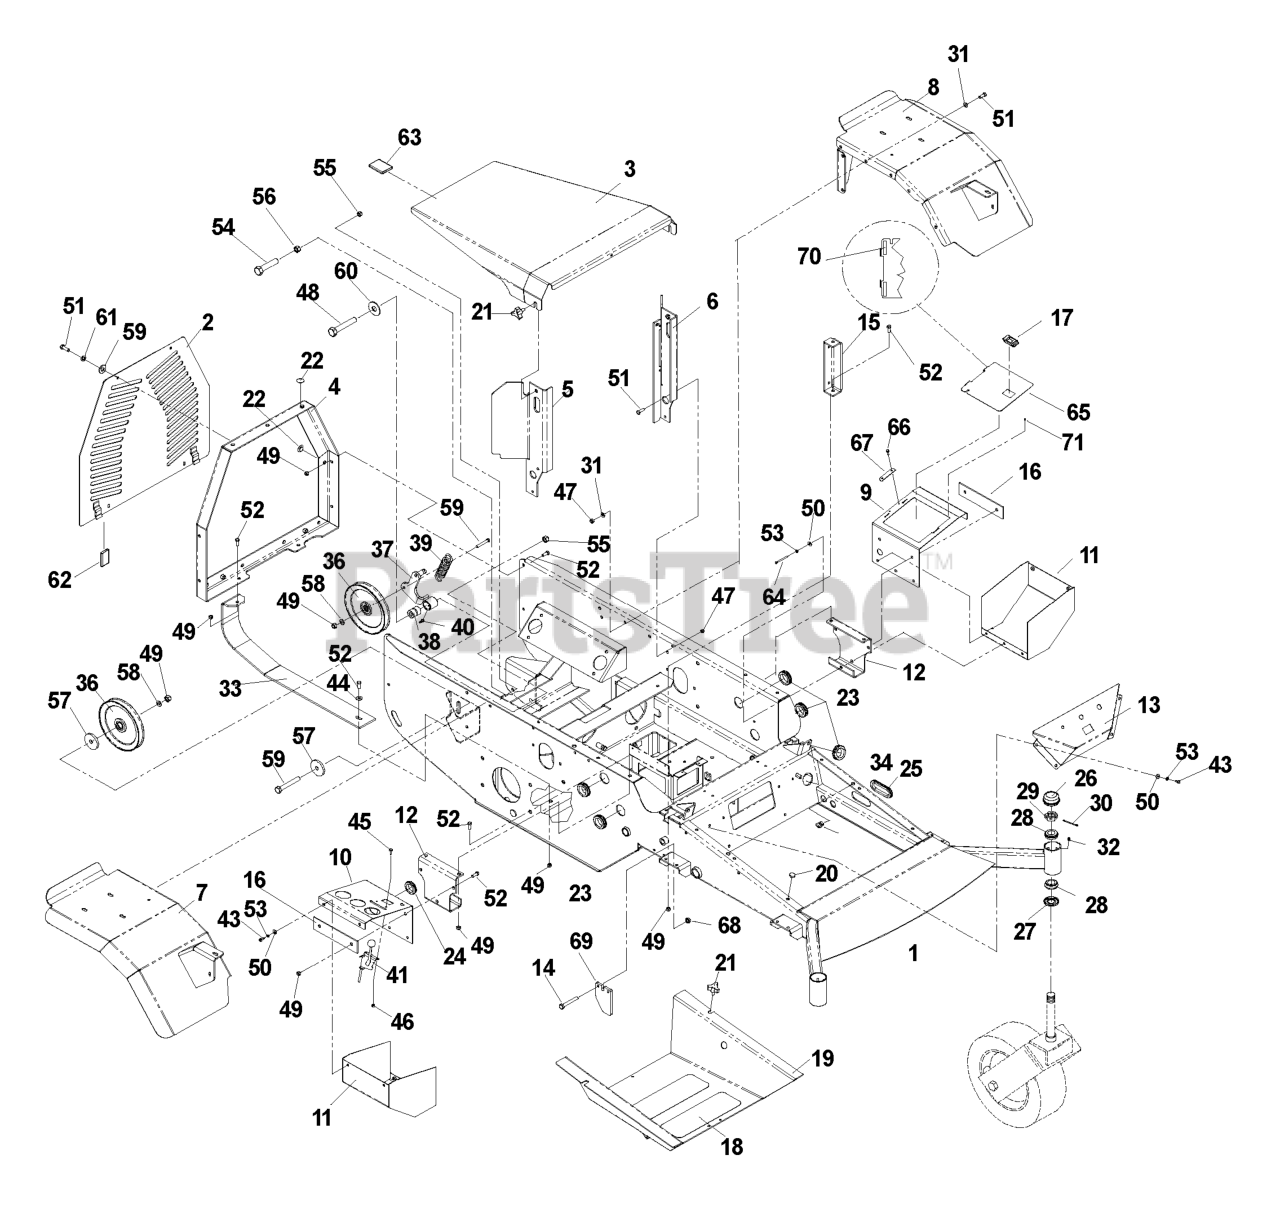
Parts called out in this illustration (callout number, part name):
1	FRAME W/DECALS
2	PANEL W/ DECALS
3	HOOD ORANGE
4	REAR FRAME
5	SUPPORT WLDMT, RT
6	SUPPORT WLDMT, LT
7	FENDER WELDMT, RH
8	FENDER WELDMT, LH
9	CONSOLE TOP-FINISHED ORANGE
10	CONTROL PANEL
11	CONSOLE BOTTOM
12	CONSOLE SUPPORT
15	SUPPORT WELDMENT
16	BLACK-STIFFNER-PAINTED
18	ANTI-SKID PAD
19	FOOTPLATE W/DECALS
20	GROMMET, BUMPER
21	KNOB W/STUD
22	GROMMET BUMPER
26	GREASE CAP
28	TAPERED ROLLER BRG
29	NUT 1"C HEX SLOTTED
30	COTTER PIN 1/8 X 2
31	FLAT WASHER 5/16 SAE
33	SKID PLATE
34	U-CLIP 5/16-18 NUT RETAINER
37	ARM WELDMENT
40	ZERK
41	THROTTLE CONTROL W/BALL KNOB
43	SCREW 1/4 X 5/8
44	WASHER 3/8 FLAT
45	HCS #10-24 X 1/2
46	NUT 10-24 NYLOC
47	NUT 5/16 NYLOC
48	HEX SCREW 1/2-13 X 2.5" GR 5
49	NUT 3/8-16 NYLOC
50	WASHER 1/4 FLAT
51	HCS 5/16C X 1
52	HCS 3/8-16X1.GRD.5.ZD
53	LOCKWASHER 1/4"
54	HCS 1/2-13X2 GR 8
55	NUT 1/2-13 HEX NYLOC ZD
56	NUT HEX 1/2
57	SPINDLE WASHER
58	WASHER 3/8 SAE FLAT
59	WASHER 5/16 FLAT
60	WASHER 1/2 FLAT
61	WASHER.LOCK.HVY.HLCL.SPR.5/16
64	HCS 1/4-20 X 3 GR 5 ZD
65	DOOR - FINISHED
66	SCR #10-12X3/4 HEX WAS HD ZD
68	NUT 5/16C WHIZ
70	FOAM STRIP
